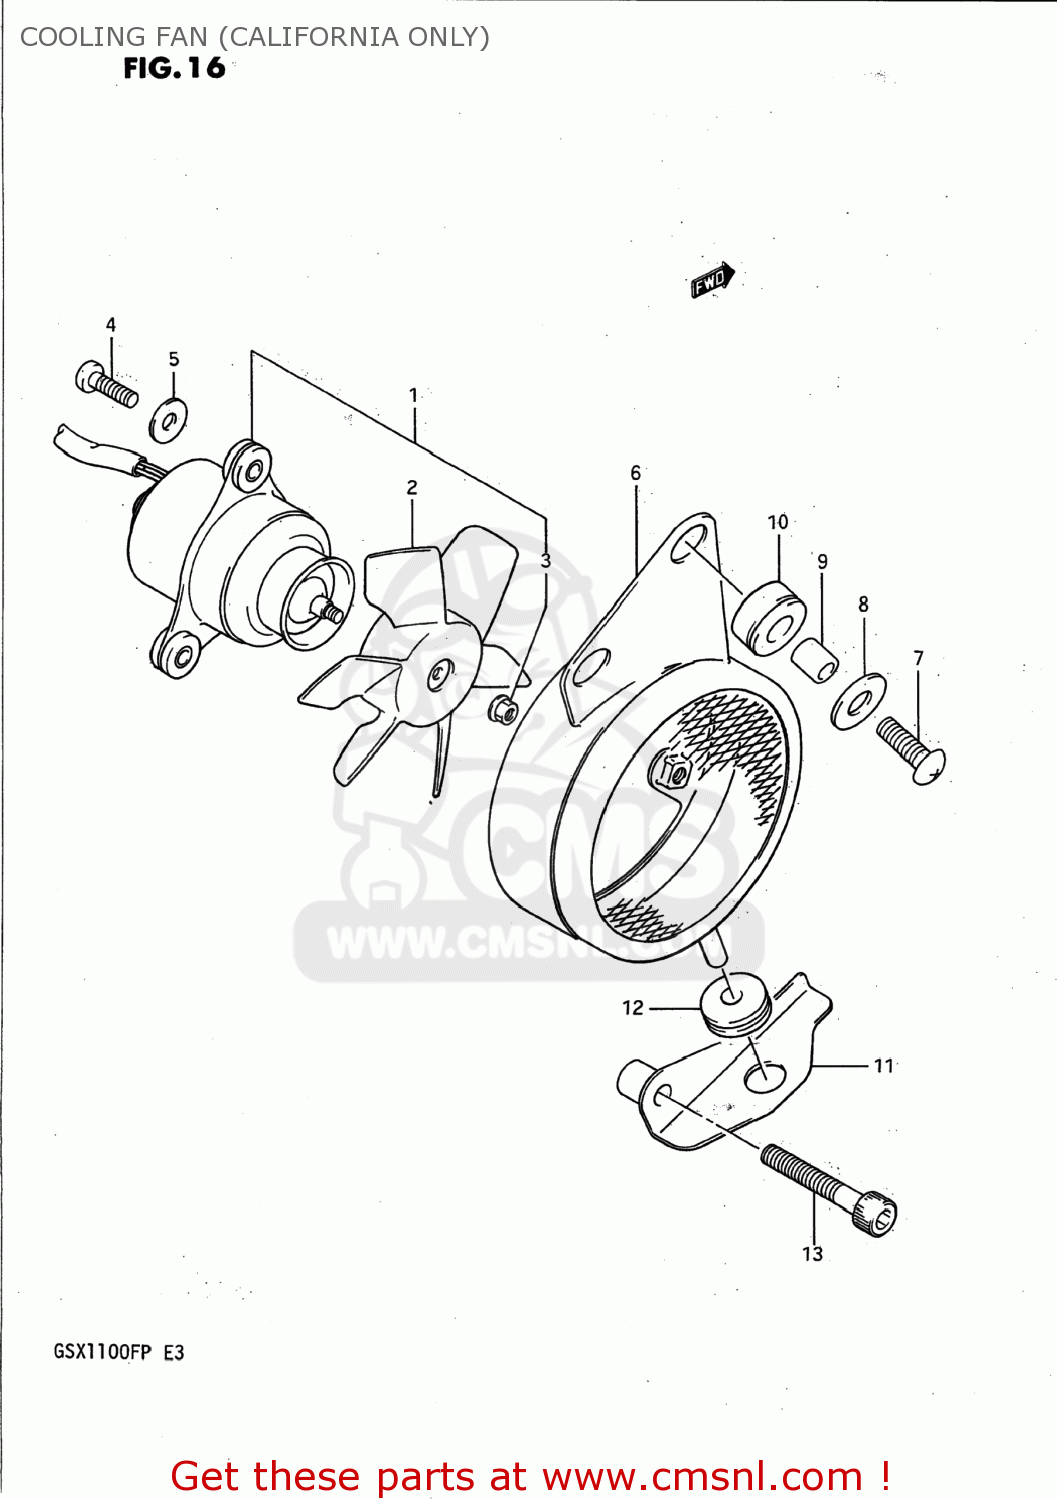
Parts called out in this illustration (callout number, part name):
1	FAN ASSY,COOLING
2	FAN
3	NUT 3MM
4	SCREW
5	WASHER (4.3X13X0.80)
6	(CA) SHROUD,FAN
7	SCREW, CENTER
8	WASHER(6.5X18X1)
9	SPACER(9.2X9X6.5)
10	CUSHION
11	(CA) BRACKET,FAN SHROUD
12	CUSHION
13	BOLT
